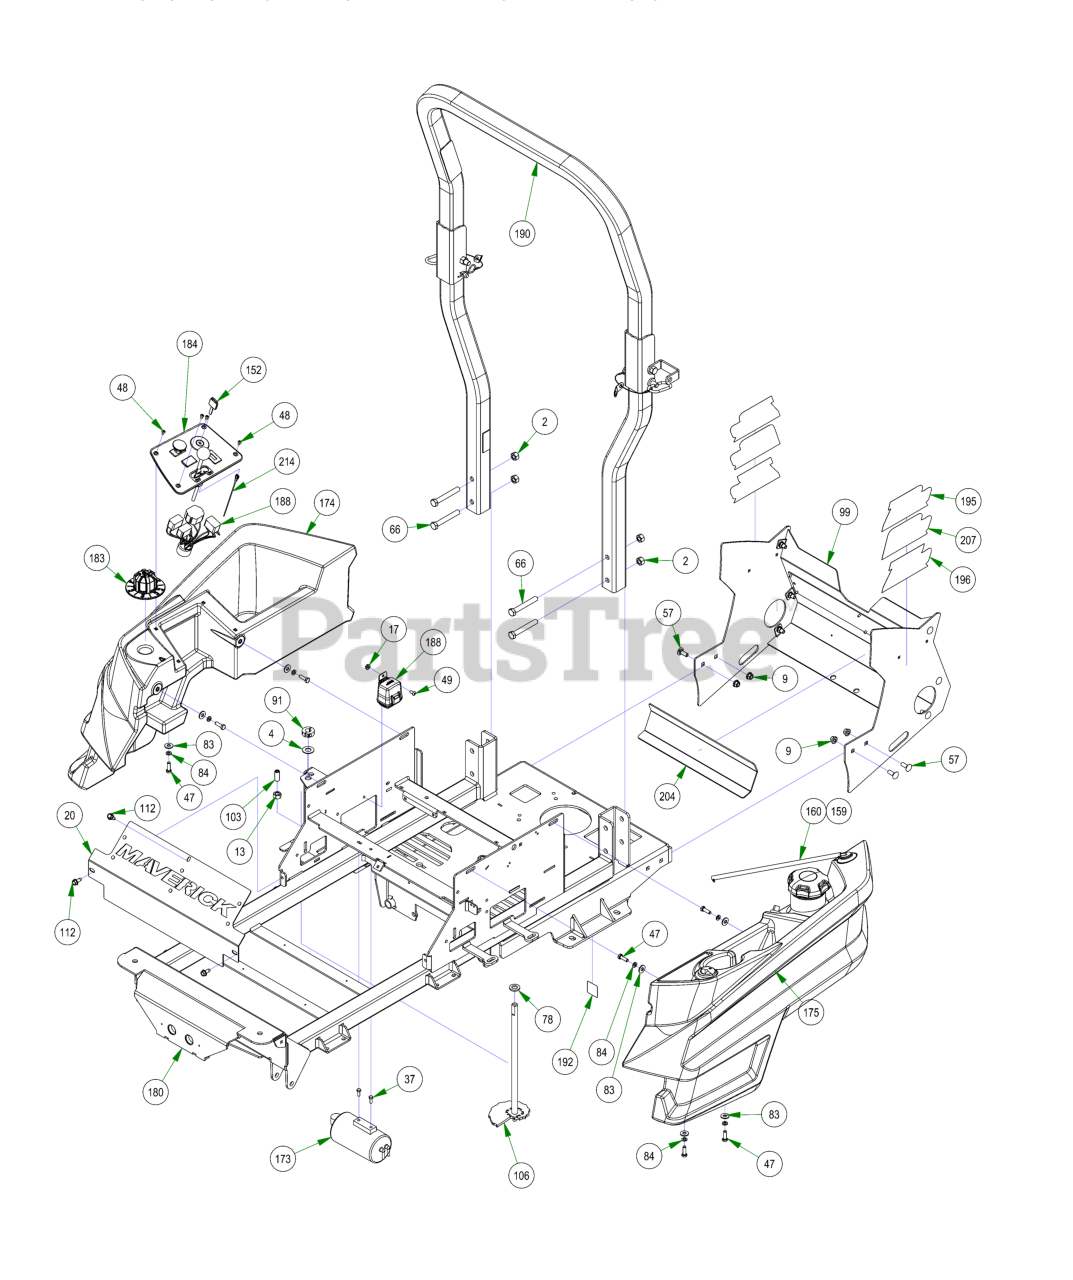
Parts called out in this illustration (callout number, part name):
2	1/2-13 HEX 2-WAY REVERSIBLE CENTER LOCKNUT Grade B ZINC
4	.625 ID x 1.250 OD x .062 THK F/W Nylon
9	3/8-16 NYLON INSERT FLANGE LOCKNUT (GR.F) ZINC
13	1/2-13 HEX NUT ZINC
17	1/4-20 HEX SERRATED FLANGE NUT HARD/ZINC
20	2021 Maverick Cooler Cover Assembly
37	M6-1.0 X 16MM DIN 933 HEX TAP BOLT (CL 8.8) ZINC
47	5/16-18 X 1 HEX CAP SCREW (GR.5) ZINC
48	10-32 X 3/8 BUTTON SOCKET CAP SCREW 18-8 STAINLESS
49	1/4-20 X 1/2 BUTTON SOCKET CAP SCREW 18-8 STAINLESS
57	3/8-16 X 1 CARRIAGE BOLT (GR.5) ZINC
66	1/2-13 X 3-1/2 HEX CAP SCREW (GR.5) ZINC
78	.635 ID X 1.120 OD X .140 THICK FLAT WASHER NYLON
83	5/16 USS FLAT WASHER (7/8 OD) ZINC
84	5/16 SPLIT LOCKWASHER ZINC
91	5/8" Split Collar
99	2022 Maverick Rear Cover Assembly
103	Dial Rod Plunger
106	ZT Deck Height Bar Assembly
112	5/16-18 X 3/4HEX WASHER SLOT (F) TCS ZINC
152	Ignition Key
159	15" Fuel Line Assembly
160	37" Fuel Line Assembly
173	ZT/Mav EPA Cannister Assy
174	2021 Maverick Right Side Tank
175	2021 Maverick Left Side Tank
180	2022 Maverick Frame - Painted
183	MZ/ZT Deck Height Dial
184	2019 ZT/Maverick Control Panel Assembly
188	Wiring Harness
190	2016 2x2 ROPS
192	Patent Decal
195	2018 Maverick 726cc Back Plate Cluster
196	2018 Maverick 747cc Back Plate Cluster
204	Heat Shield (Fiberglass Adhesive)
207	MAV 810cc back plate decal
214	2017 MZ/ZT/MAV Tach Wire Assy
